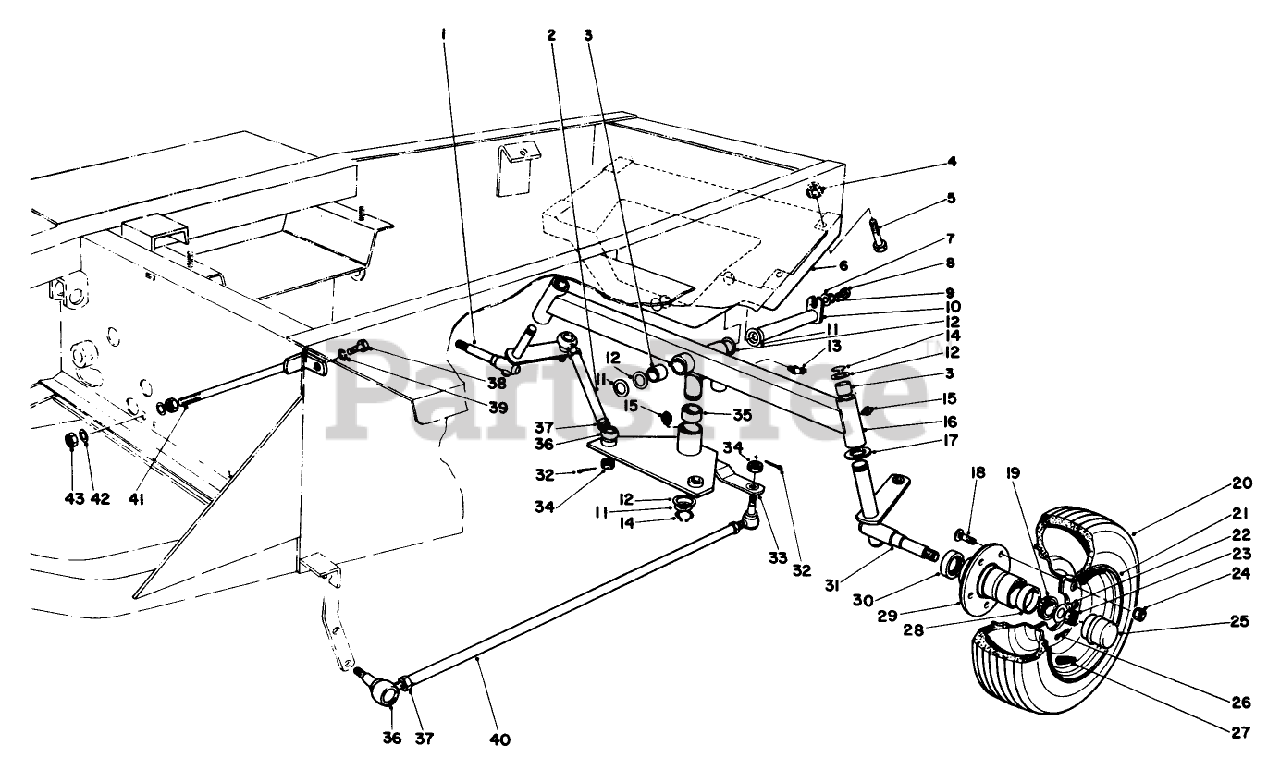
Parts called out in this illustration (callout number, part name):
1	Spindle Assembly R.H.
2	TIE ROD-STEERING
3	BUSHING
4	NUT-HF
5	SCREW-HH
6	REAR AXLE MT R
7	WASHER-PLAIN
8	SCREW-HH
9	WASHER-LOCK
10	REAR AXLE PIN WA
11	WASHER-FLAT
12	WASHER-THRUST
13	FITTING-LUBE, 45 DEG
14	RING-RETAINING
15	FITTING-GREASE
16	Rear Axle (Incl. Ref. #3)
17	WASHER-THRUST
18	STUD-TYPE, DRIVE
19	BEARING-CONE, TAPERED
20	TIRE-Ribbed
21	WHEEL-8 INCH
22	WASHER-FLAT
23	NUT-HEX, SLOTTED
24	NUT-LUG
25	CAP-DUST
26	PIN-COTTER
27	STEM-VALVE
28	BEARING-CUP, TAPERED
29	Wheel Hub (Incl. Ref. #18 & 28)
31	Spindle Assembly L.H.
32	PIN-COTTER
33	Rear Steering Pivot (Incl. Ref. #35)
34	NUT-SLOTTED
35	BUSHING
36	Socket R.H. Thread (Incl. Ref. #34)
37	NUT-JAM
38	SCREW-HH
39	WASHER-LOCK
40	REAR STRG TUBE PP
41	Axle Support
42	WASHER-FLAT
43	NUT-HH
44	WASHER
